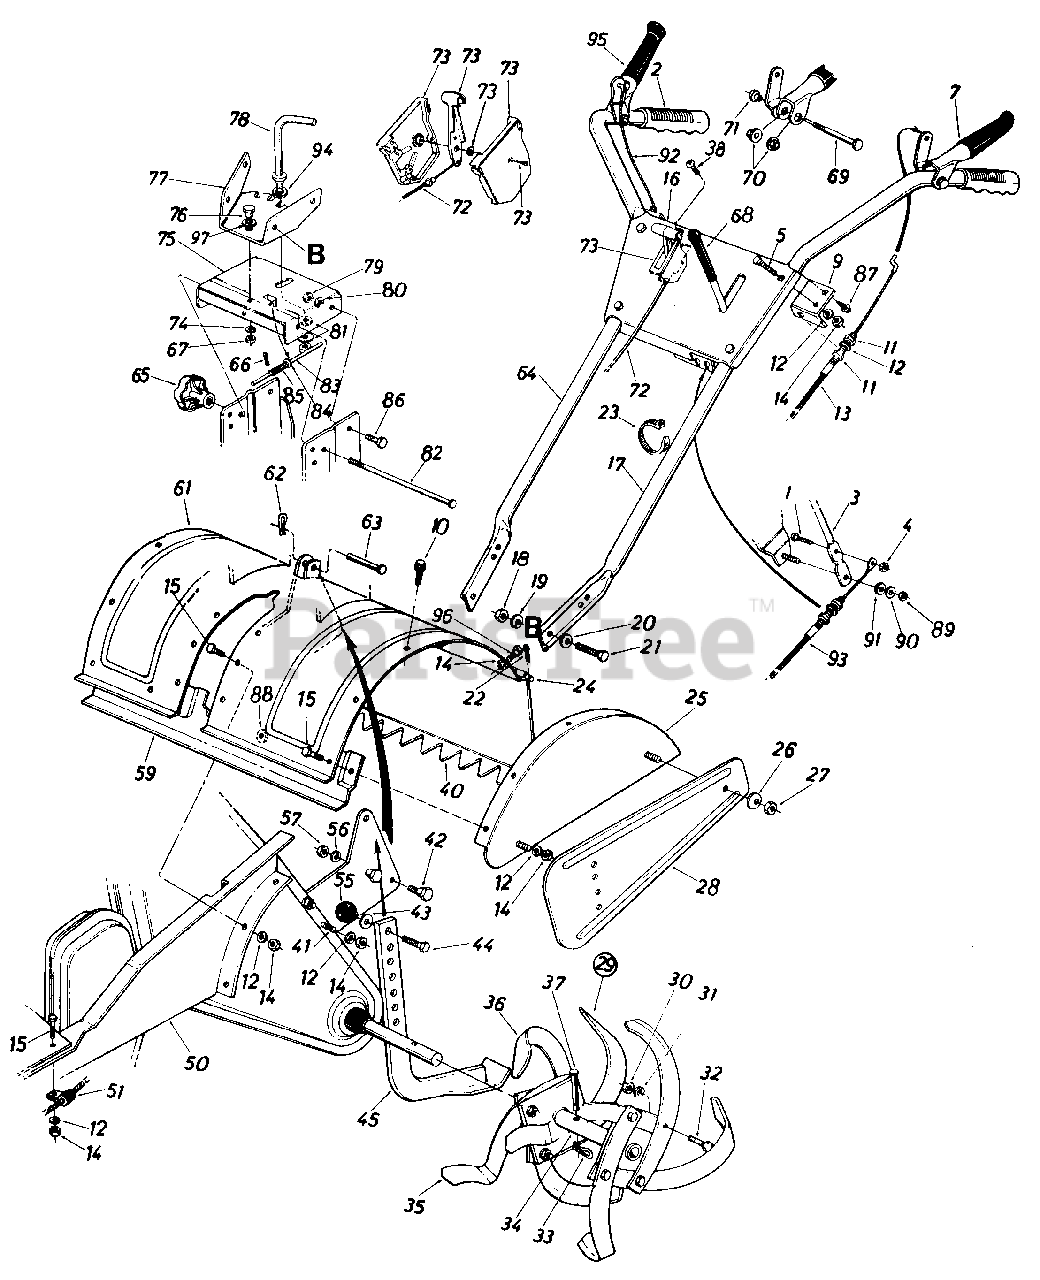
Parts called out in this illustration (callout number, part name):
1	Hex Bolt 1/4-28 x .75" Lg.*
2	Grip
3	Clutch Lever
4	Hex Cent. L-Nut 1/4-28 Thd.
5	Carr. Bolt 5/16-18 x 1.75
7	Clutch Grip Ass'y. L.H.
9	Clutch Cable Bracket
10	Hex Wash. S-Tap Scr. 5/16-18 x .62" Lg.
11	Hex Nut 5/16-24 Thd.
12	L-Wash. 6/16" I.D.
13	Clutch Control Cable
14	Hex Nut 5/16-18 Thd.
15	Hex Bolt 5/16-18 x .75" Lg.
19	L-Wash. 3/8" I.D.
20	Bell-Wash. 818" I.D.
21	Hex Bolt 3/8-16 x l" Lg.
22	Cotter Pin 8/32" Dia. x 3/4"*
23	Cable Tie
24	Tiller Flap Rod
27	Hex Nut 5/16-18 Thd.
31	L-Wash. 3/8" I.D.
32	Hex Bolt 3/8-24 x 1.25" Lg.
33	Hairpin Cotter
38	Truss Mach. AB-Tap Scr. #10 x 5" Lg
41	Hex Bolt 5/16-18 x 1.0" Lg.
42	Shld. Bolt 1/2" Dia. x .43"
43	Fl-Wash. 3/8" I.D. x 5/8" O.D.
44	Hex Bolt 3/8-16 x 3/4" Lg.
55	Ball Knob 1-1/4" Dia.
56	L-Wash. 3/8" I.D.
57	Hex Nut 3/8-16 Thd.
63	Clevis Pin 3/8" Dia.
66	Cotter Pin 1/16" Dia. x .75"
67	Hex Cent. L-Nut 3/8-16 Thd.
69	Shoulder Bolt .375" Dia. x 1.37" Lg.
70	Hex Flange Plastic Bearing
71	Shoulder Nut 1/4-20 Thd.
72	Throttle Control Wire
73	Throttle Control Box Ass'y.
74	Bell-Wash. .40" I.D. x 1.13"
79	Hex Cent. L-Nut 3/8-16 Thd.
80	Bell-Wash. 40" I.D. x .88"
81	Bell-Wash. 1/2" I.D. x 1.00"
82	Lock Pin 5/16" Dia. x 3"
83	Lower Sliding Ass'y.
84	Fl-Wash. .291" I.D. x .62"
85	Compression Spring 1" Lg.
86	Shoulder Bolt 1/2" Dia. x .1 70" Lg.
87	Hex Wash. S-Tap Scr. 1/4-20 x .50" Lg.
88	Bell-Wash. 5/16" I.D.
89	Hex Cent. L-Nut 5/16-18 Thd.
90	Fl-Wash. .344" I.D. x .87"
91	Rubber Wash. .33 I.D. x 37"
92	Control Cable
93	Control Cable
94	Fl-Wash. .62" I.D. x 1.57"
95	Clutch Grip Ass'y. R.H.
96	Hex Bolt 5/16-18 x 1.25"
97	Fl-Wash. .64" I.D. x .94"
